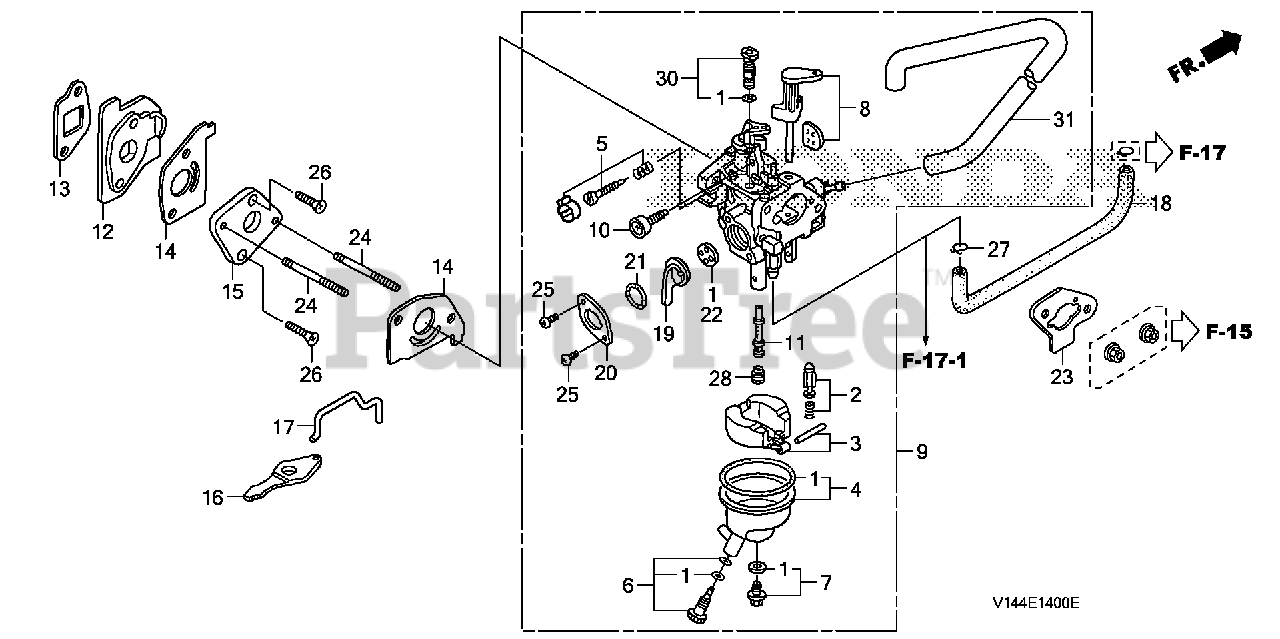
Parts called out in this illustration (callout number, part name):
1	GASKET SET
2	VALVE SET, FLOAT (SEAT NOT INCLUDED)
4	CHAMBER SET, FLOAT
6	SCREW SET, DRAIN
7	SCREW SET
9	CARBURETOR ASSY. (BF24A B)
10	SCREW, THROTTLE STOP
11	NOZZLE, MAIN
12	INSULATOR, CARBURETOR
13	GASKET, INSULATOR
14	GASKET, CARBURETOR
15	PLATE, CARBURETOR JOINT
18	TUBE A, FUEL
19	LEVER, PETCOCK
20	PLATE, LEVER SETTING
21	SPRING, PETCOCK LEVER
22	GASKET, PETCOCK
23	GASKET, AIR CLEANER
24	BOLT, STUD (5X81)
25	SCREW, PAN (3X5)
26	SCREW, FLAT (5X20)
27	CLIP, TUBE (B8)
28	JET, MAIN (#45)
28	JET, MAIN (#48)
28	JET, MAIN (#50)
30	JET SET, PILOT (#35)
31	BULK HOSE, VINYL (3X6X1000) (3X6X120)
